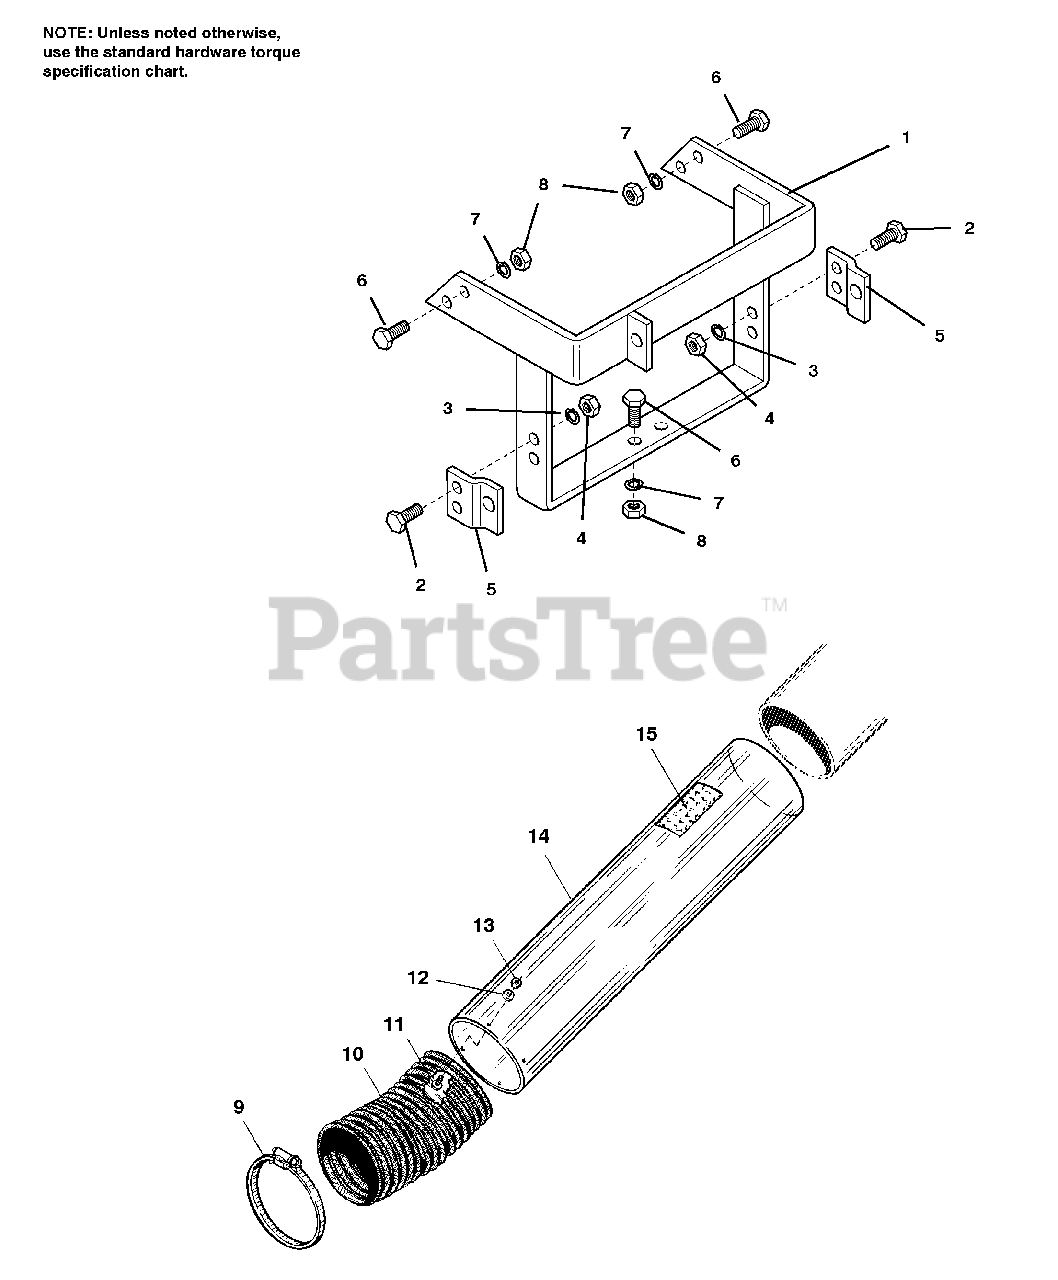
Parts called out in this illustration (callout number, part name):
1	HITCH ASSEMBLY
2	CAPSCREW, Hex Hd, 5/8-11 x 1-1/4
3	WASHER, Lock, 5/8
4	NUT, Hex, 5/8-11
6	CAPSCREW, Hex Hd, 1/2-13 x 1-1/4
7	WASHER, Lock, 1/2
8	NUT, Hex, 1/2-13
9	CLAMP, Hose, 6"
10	HOSE, 6" Dia.
11	CAPSCREW, Truss Hd, #10-32 x 1/2
12	WASHER, Plain, 3/16
13	NUT, Hex Lock, #10-32
14	TUBE & DECAL ASSEMBLY
15	DECAL, Cleaning
